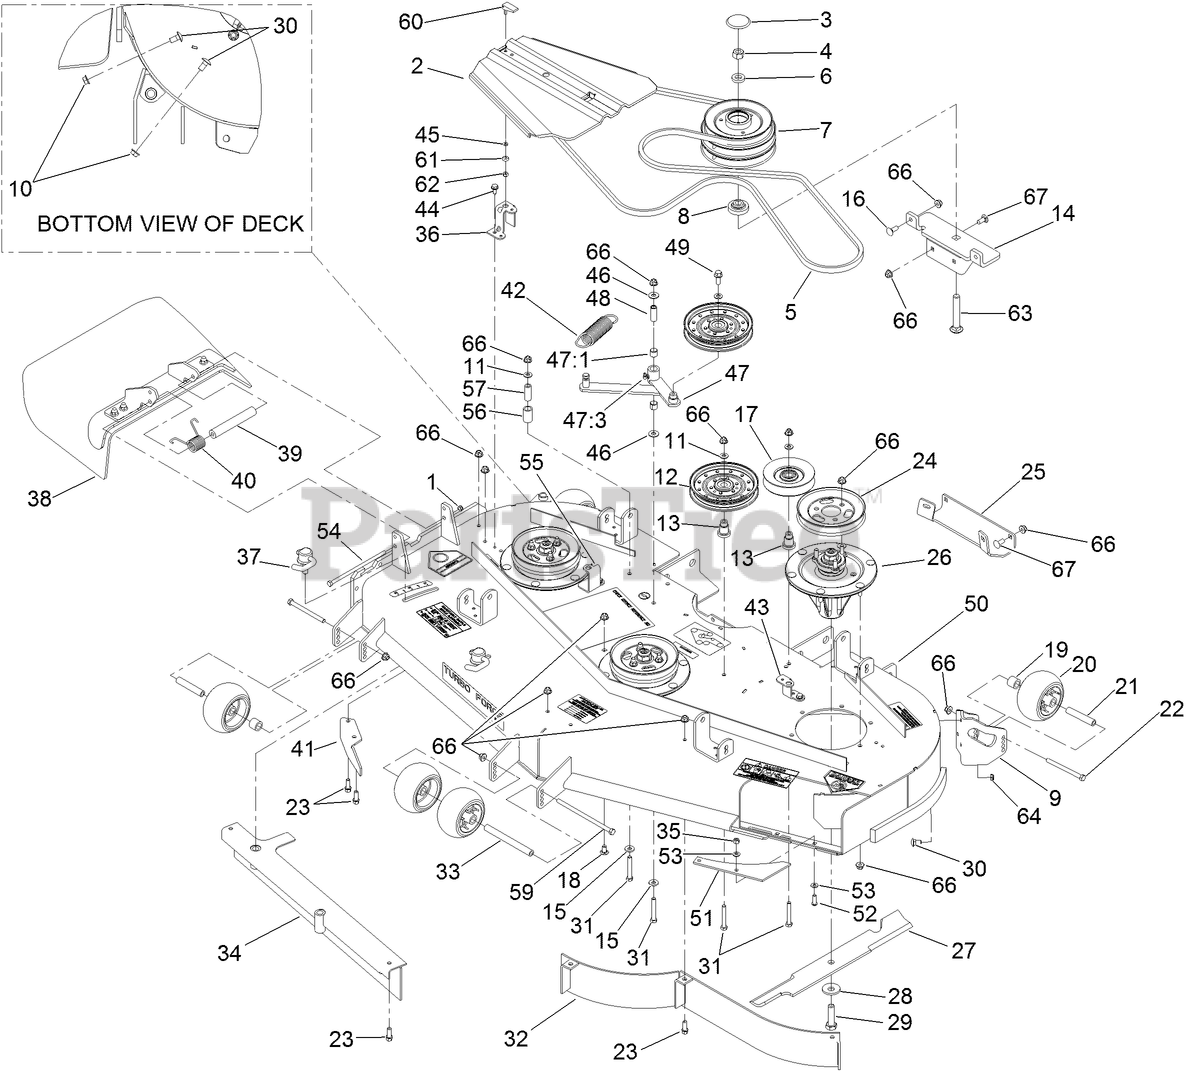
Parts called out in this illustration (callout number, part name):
1	NUT-LOCK, NI
2	COVER-BELT
3	CAP-PLASTIC
4	NUT-HEX
5	BELT-V
6	SPACER
7	PULLEY AND BEARING ASM
8	SPACER-FLANGED
9	MOUNT-WHEEL, LH
10	NUT-HHF, WHIZ
11	WASHER-FLAT
12	Idler-Flat
13	MOUNT-PULLEY
14	MOUNTING BRACKET ASM
15	WASHER-BELLEVILLE
16	BOLT-CARR
17	PULLEY-IDLER
18	SCREW-CARR
19	TUBE-SPACER
20	ROLLER-SCALP, ANTI
21	TUBE-SPANNER
22	SCREW-HH
23	SCREW-HWH
24	Pulley
25	Plate-Skid
26	SPINDLE ASM
27	BLADE-HI FLOW
28	Washer-Blade Bolt, Heavy
29	SCREW-BLADE
30	SCREW-CARR
31	SCREW-HH
33	SPACER-WHEEL
35	NUT-LOCK, NI
36	BRACKET-COVER
37	LEVER ASM
38	RUBBER DEFLECTOR ASM
39	SPACER
40	SPRING-TORSION
41	BAFFLE-DISCHARGE
42	SPRING-EXTENSION
43	BRACKET-COVER, TALL
44	SCREW-HWHTF
45	WASHER
46	WASHER-FLAT
47	IDLER ARM ASM
47:1	SLEEVE-BEARING
47:3	FITTING-GREASE, 90 DEG
48	BUSHING
49	SCREW-HHF
50	DECK DECAL ASM
51	PLATE-TURBO
52	SCREW-HSBH
53	WASHER-SPRING
54	SCREW-HH
55	BRACKET-COVER
56	SPACER-RUBBER
57	SPACER-PIVOT, IDLER
59	SCREW-HH
60	HANDLE-LATCH, SWELL
61	BUSHING-LATCH, SWELL
62	NUT-LOCK, HH
63	BOLT-CARRIAGE
64	NUT-LOCK, NI
66	NUT-HF, NI
67	SCREW-CARR
